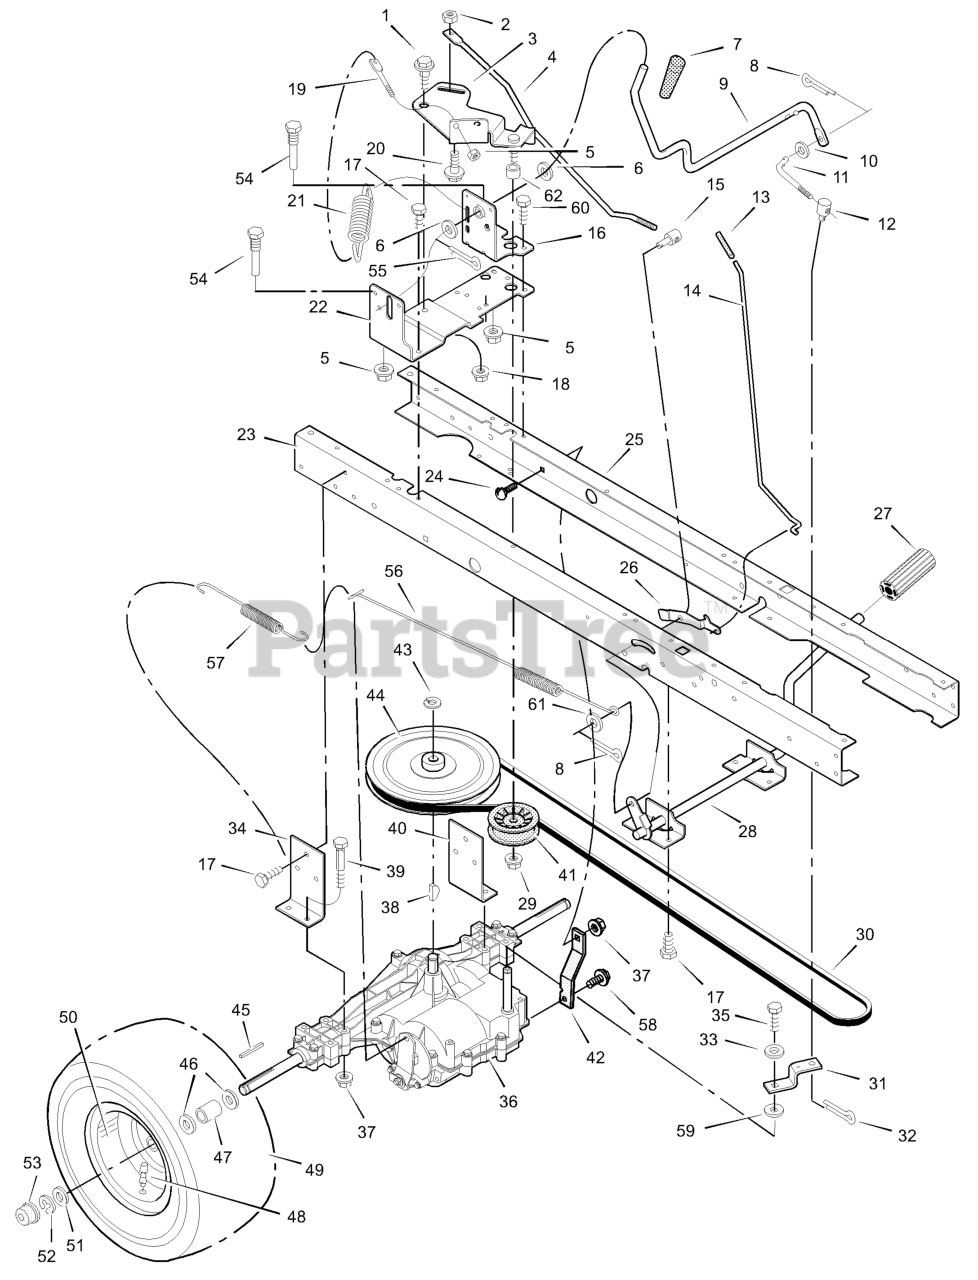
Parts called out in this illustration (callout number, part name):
1	Bolt, Shoulder
2	Nut, Hex
3	ARM, Idler
4	Rod, Clutch
5	Nut
6	Washer
7	Grip
8	Pin, Cotter
9	Lever, Shift
10	Washer
11	Link, Shift
12	Nut, Adjuster
14	Rod, Parking Brake
15	Nut, Adjuster
16	Bracket, Shift Pivot
18	Nut
19	Mount, Stud Spring
20	Bolt, Shoulder
21	Spring, Extension
22	Bracket, Right Shifter
23	Frame, Right
24	Bolt, Carriage
25	Frame, Left
26	Latch, Parking Brake
27	Pedal
28	Lever, Brake/Clutch
29	Nut
30	Belt, Motion Drive
31	Yoke, Shift
32	Pin, Hair
34	Bracket, Right Transaxle
36	Transaxle **
37	Nut
38	Key, Woodruff
39	Bolt
40	Bracket, Left Transaxle
42	BRACKET, Torque Strap, LH
44	Pulley, Drive
45	Key, Square
47	Spacer, Transaxle
48	Stem, Valve
50	Wheel & Tire Assembly
53	Hub Cap
54	Guide, Belt
55	Pin, Hair
56	Spring, Extension
57	Spring, Extension
61	Washer
